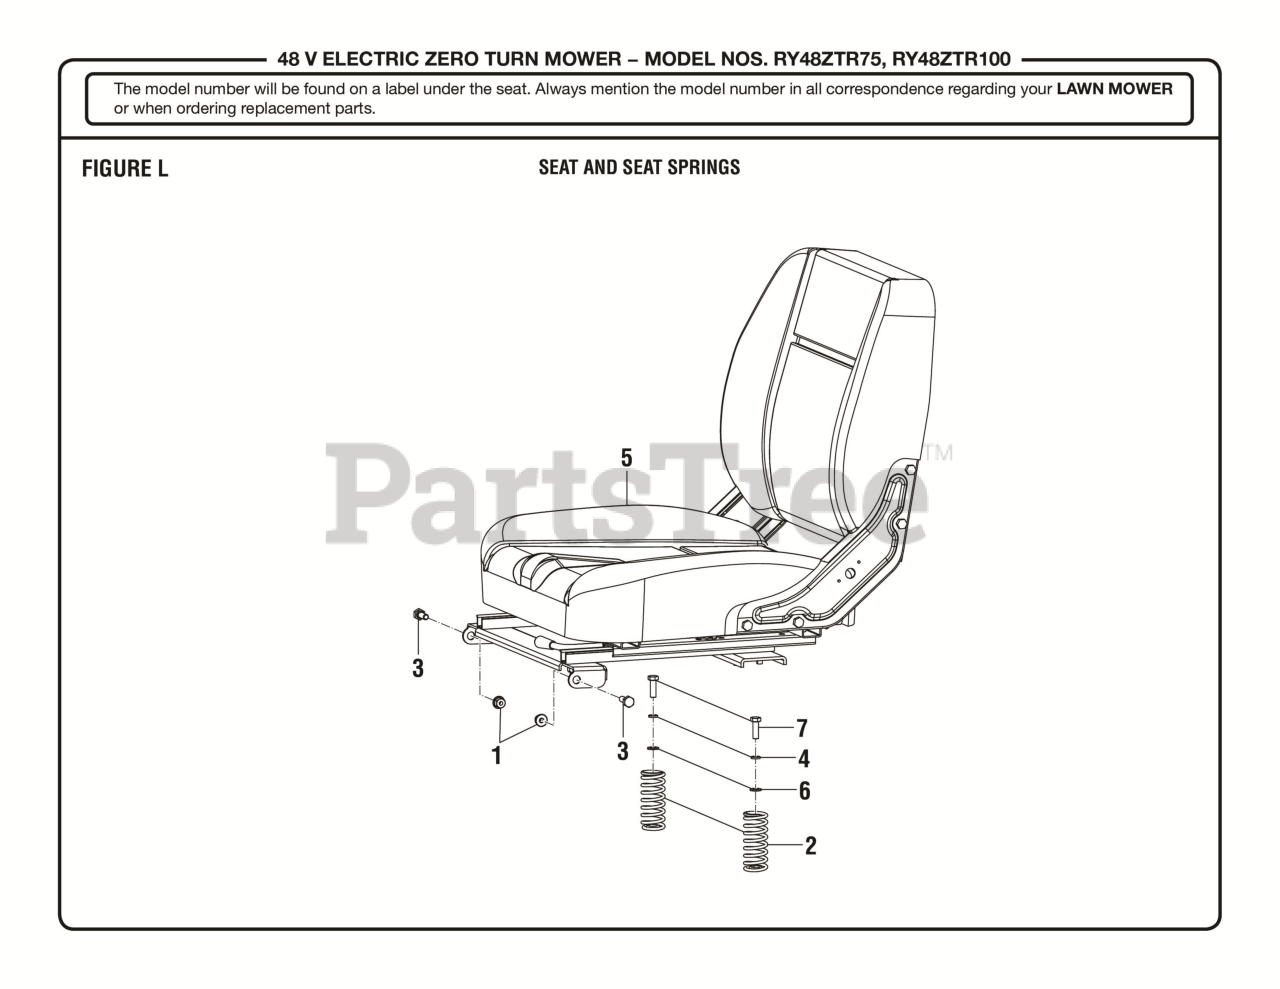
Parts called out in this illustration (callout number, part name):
1	Flange Nut (M8) (For Drive Motor Controller V)
2	Seat Spring, ZTR
3	Shoulder Bolt (M8 x 20 mm)
4	Lock Washer (OD9.8 x ID8.5 x 5t)
5	Seat, ZTR
6	Washer (OD16 x ID8.4 x 1.6t)
7	Bolt (M8 x 25 mm, Hex Hd.)
